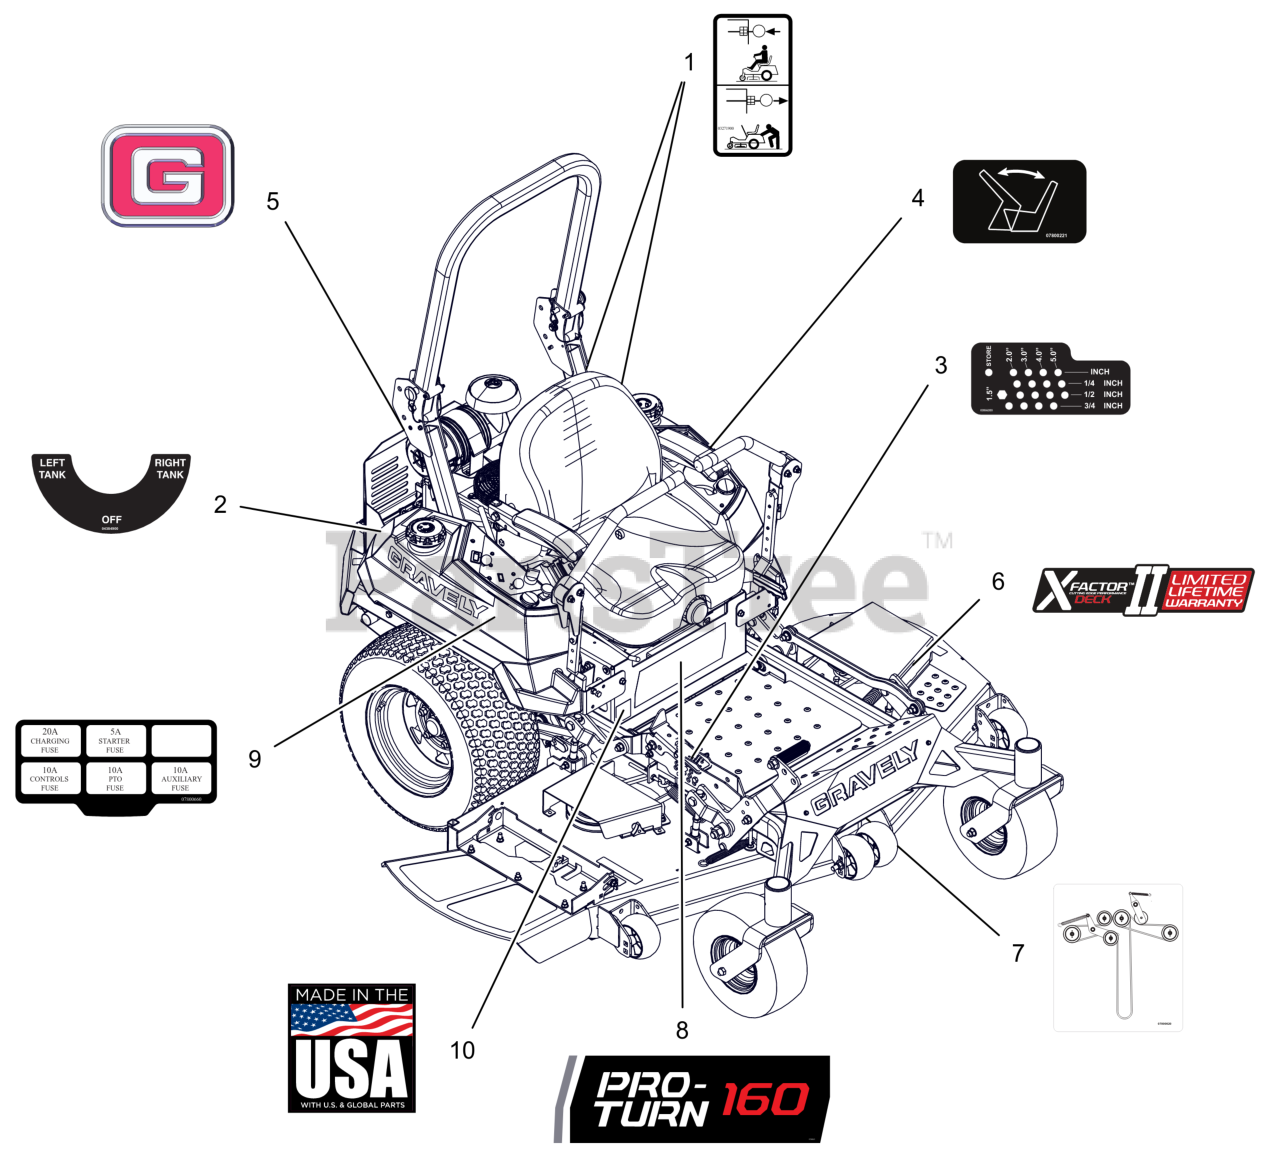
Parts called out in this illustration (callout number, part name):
1	DECAL, TRANSMISSION DISCONNECT
2	DECAL, FUEL VALVE
3	DECAL, HEIGHT OF CUT
4	DECAL - SEAT RELEASE
5	DECAL, GRAVELY BRAND
6	DECAL, X-FACTOR DECK
7	DCL,BELT ROUTE-RH BK-SIDE IDLR
8	DECAL, PRO-TURN 160
9	DECAL, FUSE BLOCK
10	DECAL, MADE IN USA
